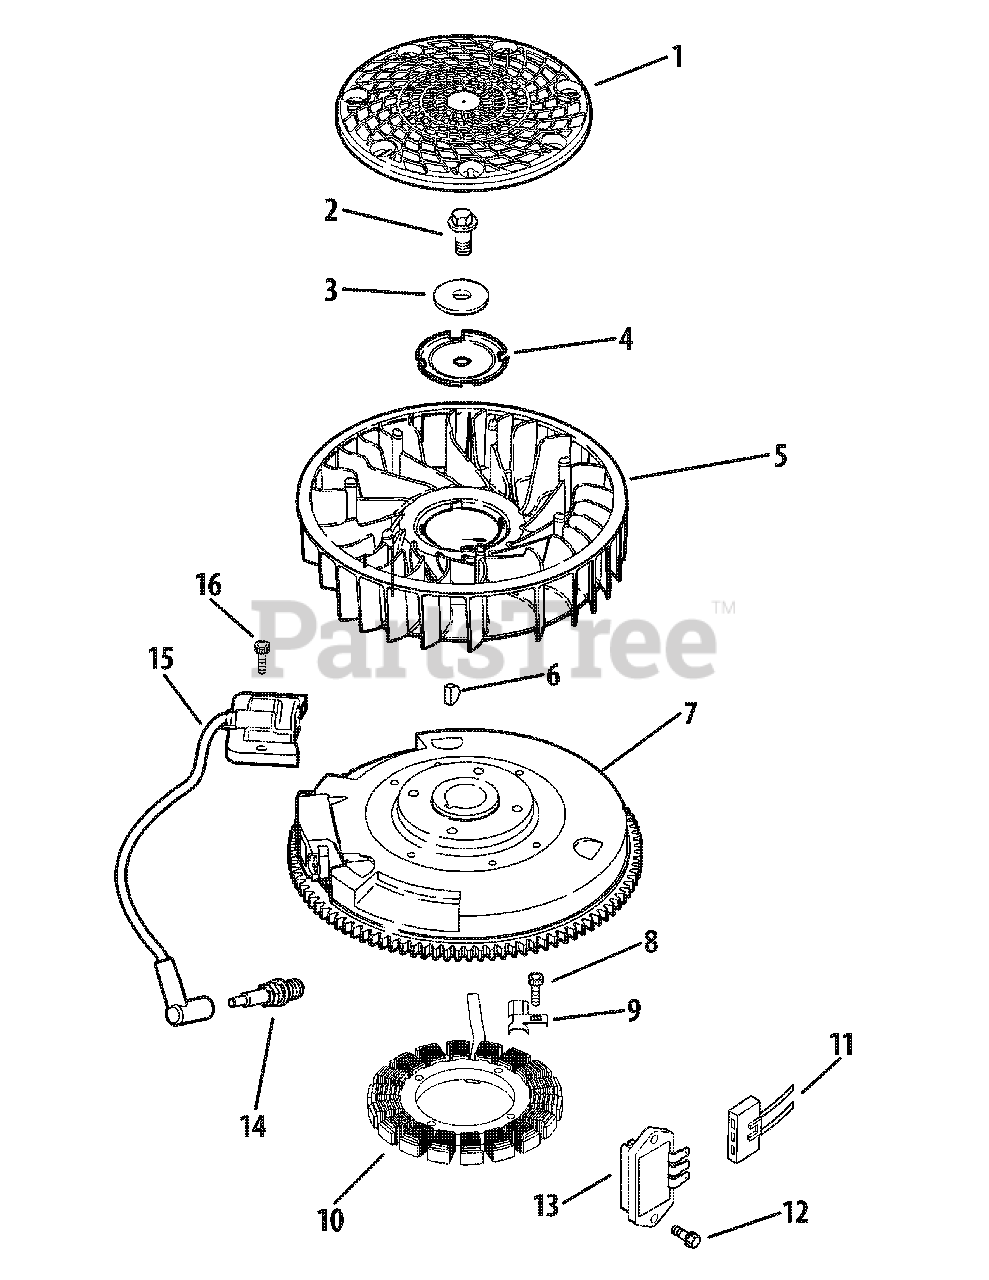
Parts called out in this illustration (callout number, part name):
2	Flg Screw, M10 x 1.5 x 45
3	Flat Washer, 13/32"
4	Fan Mounting Plate
6	Key, 3/16" x 5/8"
7	Flywheel
8	Skt Thd Frm Screw, M5 x 0.8 x 25
9	Sator Wire Clip
10	15 Amp Stator Kit
11	Connector (3 Contact)
12	Flg Thd Frm Screw, M5 x 0.8 x 20
13	Rectifier-Regulator
14	Spark Plug
15	Ignition Module
16	Skt Thd Frm Screw, M5 x 0.8 x 25
